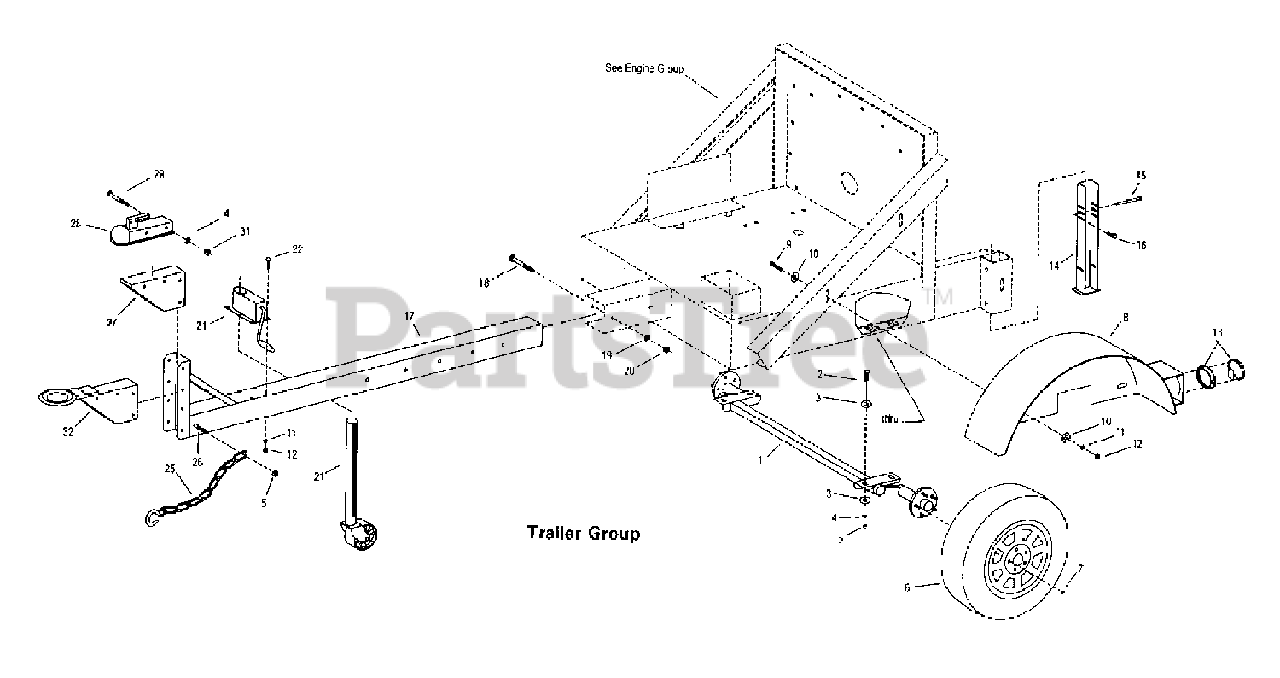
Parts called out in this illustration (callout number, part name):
1	Torflex Axle
2	1/2-13 x 1-1/4 Hex Bolt
3	1/2 Flat Washer
4	1/2 Lock Washer
5	1/2-13 Hex End Lock Nut
6	F78 x 15 Tire and Wheel Assembly
7	1/2-20 Lug Nut
8	Fender - Left Side
9	3/8-16 x 1 Hex Bolt
10	3/8 Flat Washer
11	3/8 Split Lock Washer
12	3/8-16 Hex Nut
13	Tail Lamp (w/Rubber Mounting Ring)
14	Support Leg
15	3/8 x 4 Clevis Pin
16	Bridge Pin
17	Draw Bar - Swing Jack Style
18	5/8 x 4-1/2 Hex Bolt
19	5/8 Split Lock Washer
20	5/8 Lock Nut
21	Jack Assembly, Trailer Support Swing Away Style
22	3/8-16 x 5 Hex Bolt
25	Chain, Safety w/1 S-Hook
26	HHCS, 1/2-13 x 5 YZ
27	Ball Hitch Mount, Black
28	Ball Hitch
29	1/2-13 x 3-1/2 Hex Bolt
31	1/2 Lock Nut
32	Pintle Ring (Optional)
